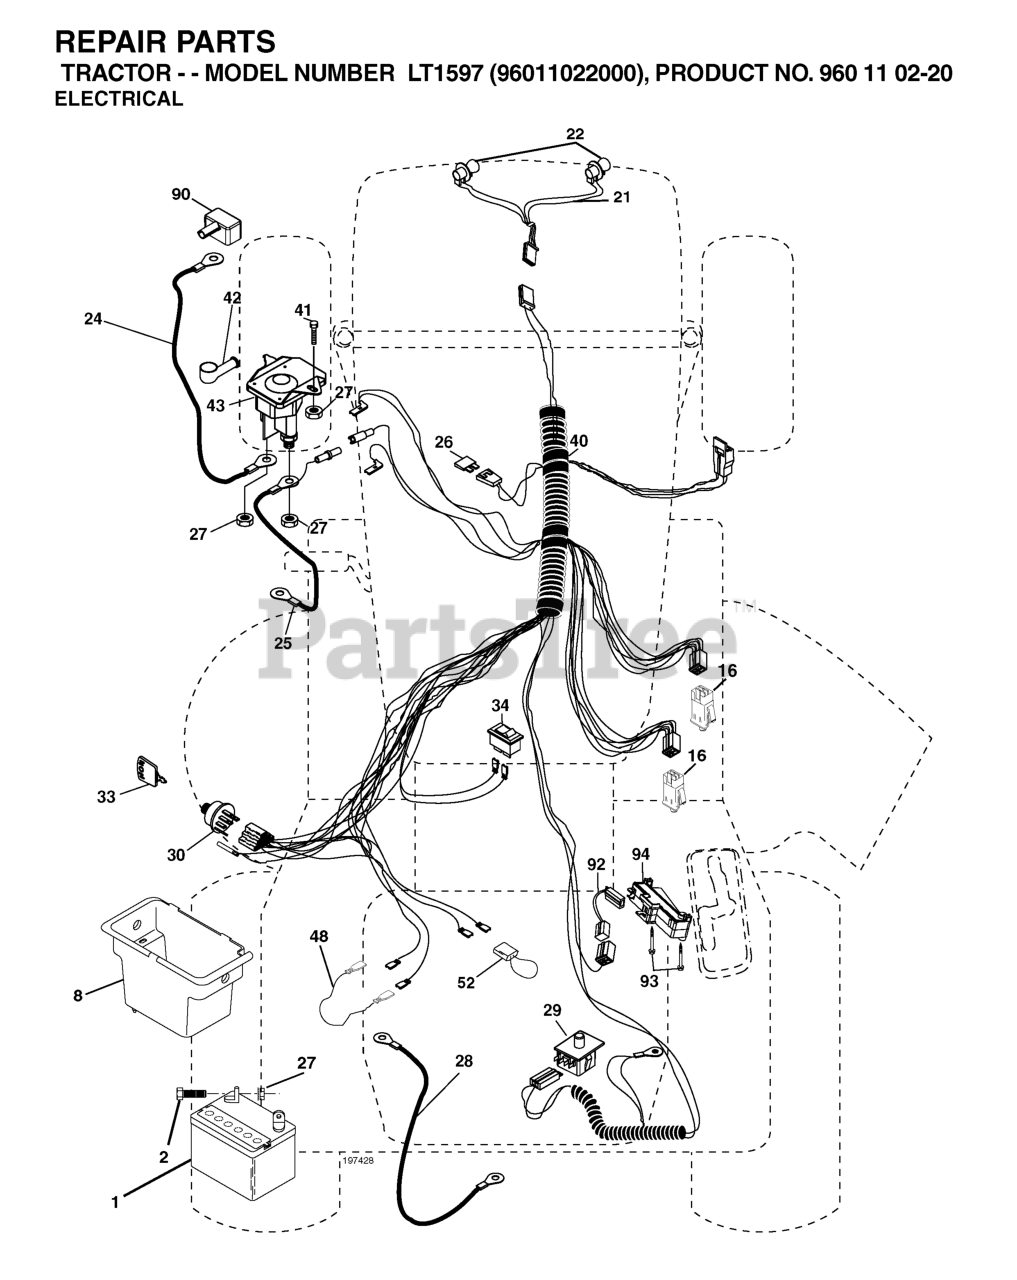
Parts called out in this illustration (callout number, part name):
1	BATTERY 12V .35 AMP
2	BOLT.HEX.1/4.X.3/4.DICHROMATE
8	BOX.BATTERY.FENDER
16	SWITCH INTERLOOK PUSH-IN
21	HARNESS.W/LIGHT SOCKET
24	BATTERY CABLE GT
25	CABLE BATTERY
26	FUSE 20AMP
27	NUT
28	CABLE T
29	SWITCH.SEAT.DP W/RAMPS
30	SWITCH.IGN.DELTA.W.LGH.ROS
33	KEY MLD GEN DELTA
40	HARNESS.IGN.CABLE.REG.
41	BOLT
42	TERMINAL COVER
43	SOLENOID.W/BRASS.PLUNGER
48	ADAPTER.AMMETER
52	WIRE PROTECTION LOOP
90	COVER TERMINAL
92	HARNESS.PIGTAIL.CONSLE
93	SCREW.PLASTITE
94	MODULE.REVERSE.ROS
